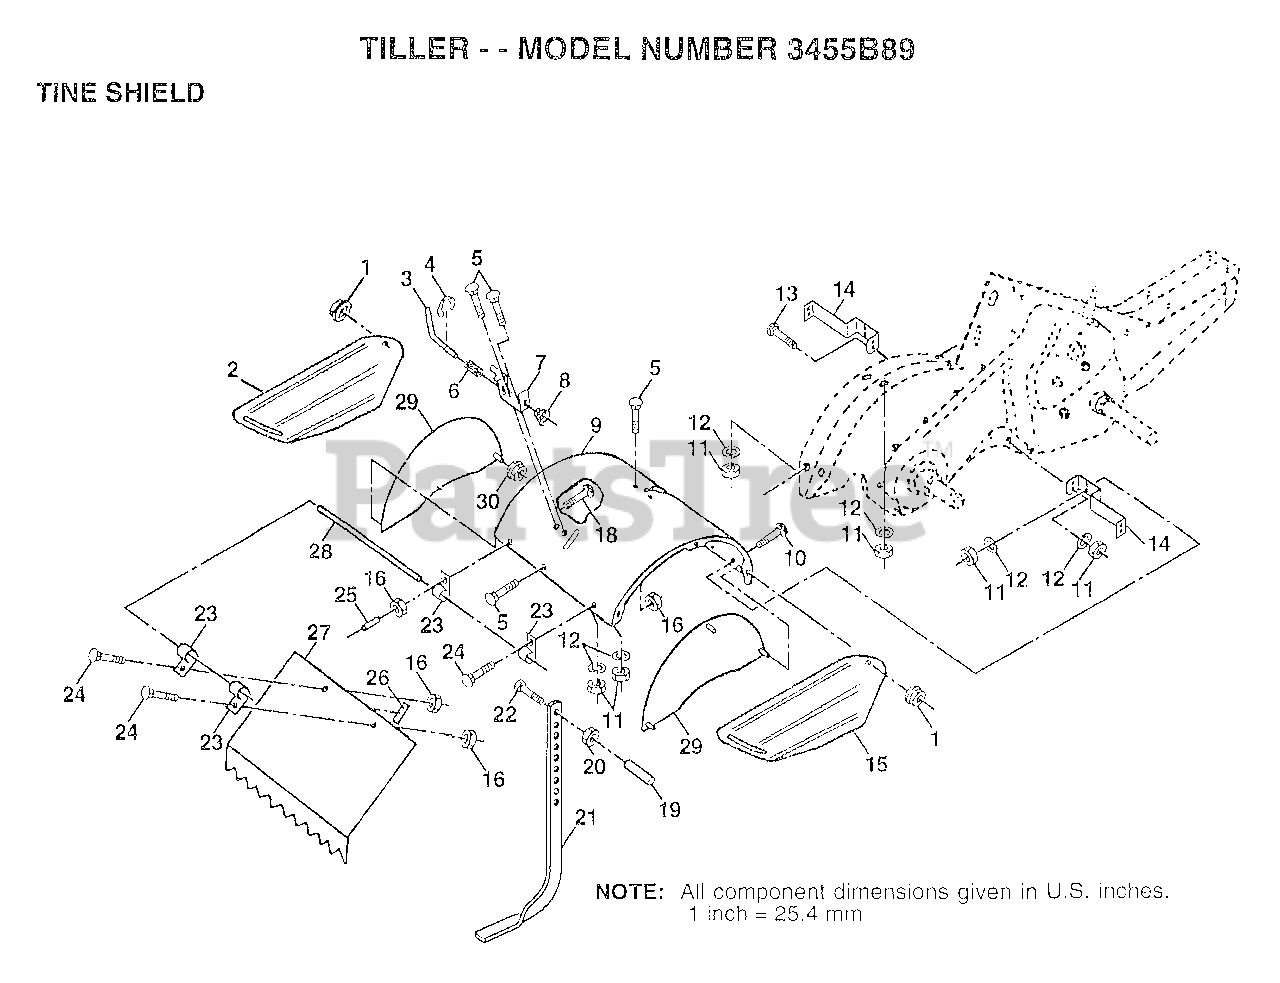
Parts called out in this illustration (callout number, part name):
1	NUT
2	"SHIELD,SIDE,O.LH"
3	STAKE PIN TI
4	KLIP RING TI
5	BOLT
6	SPRING TI
7	LATCH BRACKET TI
8	SPRING CRT
9	TINE SHIELD
10	BOLT
11	NUT.HEX.5/16-18
12	LOCKWASHER
13	BOLT
14	"BRACKET,SHIELD"
15	SHIELD SIDE O.RH
16	NUT
18	BOLT
19	GRIP CRT
20	NUT.HEX.3/8-16UNC
22	BOLT
23	HINGE CRT
24	BOLT
25	VINYL CAP TI
26	PAD IDLER TI
27	LEVELING SHIELD
28	PIN HINGE
29	SIDE SHIELD
30	LOCKNUT TI
